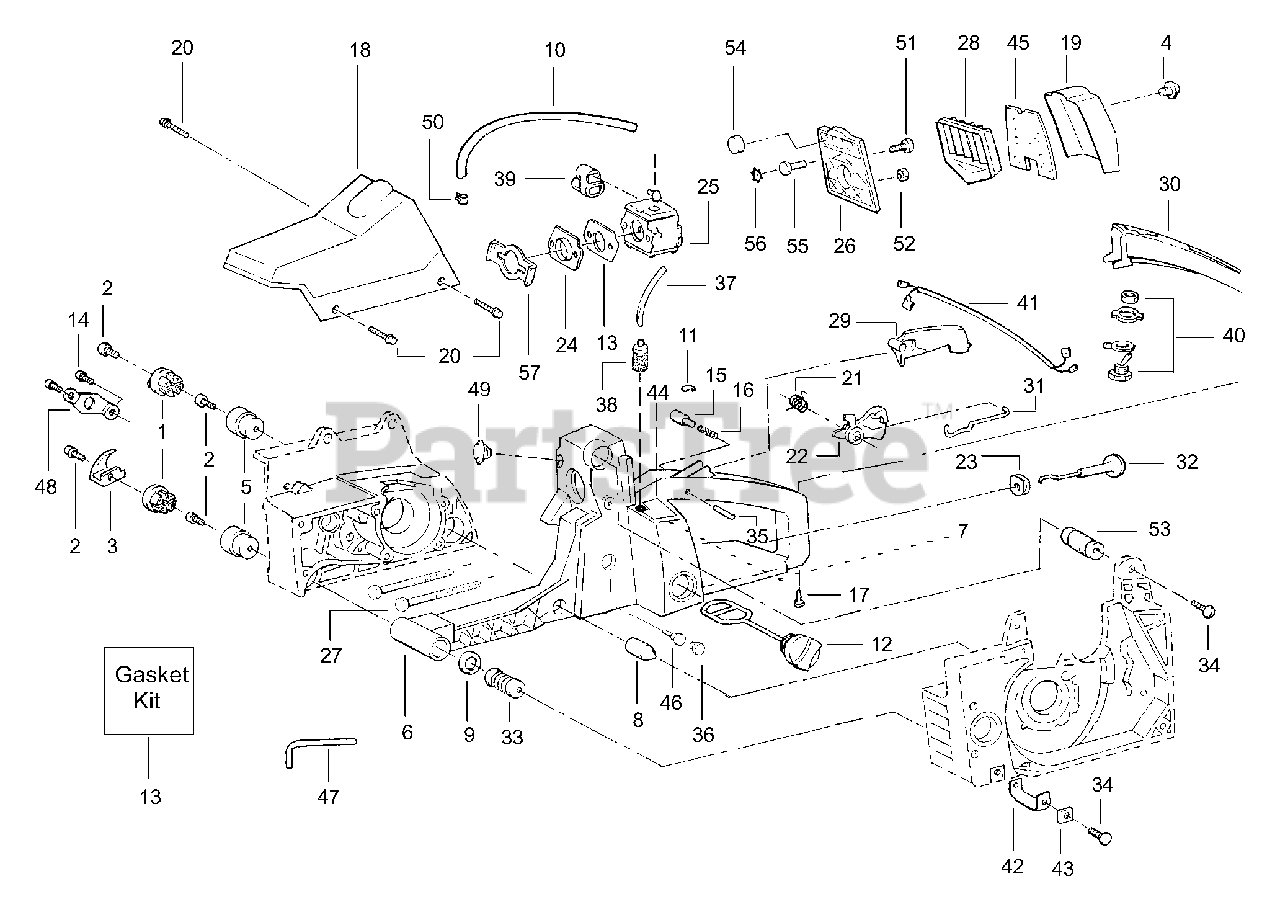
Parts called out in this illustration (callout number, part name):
1	Retainer-Chain Catcher
3	Chain Catcher
4	Knob-Carb. Cover
5	Lower Isolator
6	Tank & Handle Kit
7	Seal Carb. Cover-Left
8	Isolator-Bumper
10	Impulse Line Kit
11	"C" Clip
12	Fuel Cap Ass'y.
13	Gasket Kit
15	Button-Throttle Lock
16	Spring-Throttle
18	Cylinder Shield (Purple)
18	Cylinder Shield (Black)
19	Carb. Cover Ass'y. (Purple)
19	Carb. Cover Ass'y. (Black)
21	Trigger Latch Spring
22	Throttle Trigger
23	Grommet-Choke Rod
24	Bracket-Intake
25	Carburetor Kit (HDA-164)
26	Air Filter Base
27	Carb. Mounting Stud
28	Air Filter
29	Throttle Lockout
30	Rear Handle Cover (Purple)
30	Rear Handle Cover (Black)
31	Throttle Wire
32	Choke Knob
33	Isolator Kit
34	Screw
35	Dowel Pin
36	Plug-Bronze Vent
37	Fuel Line Kit
38	Fuel Filter Ass'y.
39	Carb. Grommet
40	Switch Kit
41	Lead Wire Ass'y.
42	AV Strap
43	Strap Retainer Plate
44	Seal Carb Cover-Right
45	Sound Foam
46	Check Valve
47	Hex Wrench 5/32
49	Plug-Air Box
51	Screw-Air Filter Base
52	Nut-Air Filter
53	Cylinder Mount Ass'y.
55	Screw-Carb Knob
56	Retaining Ring
57	Bracket-Carb Stud
